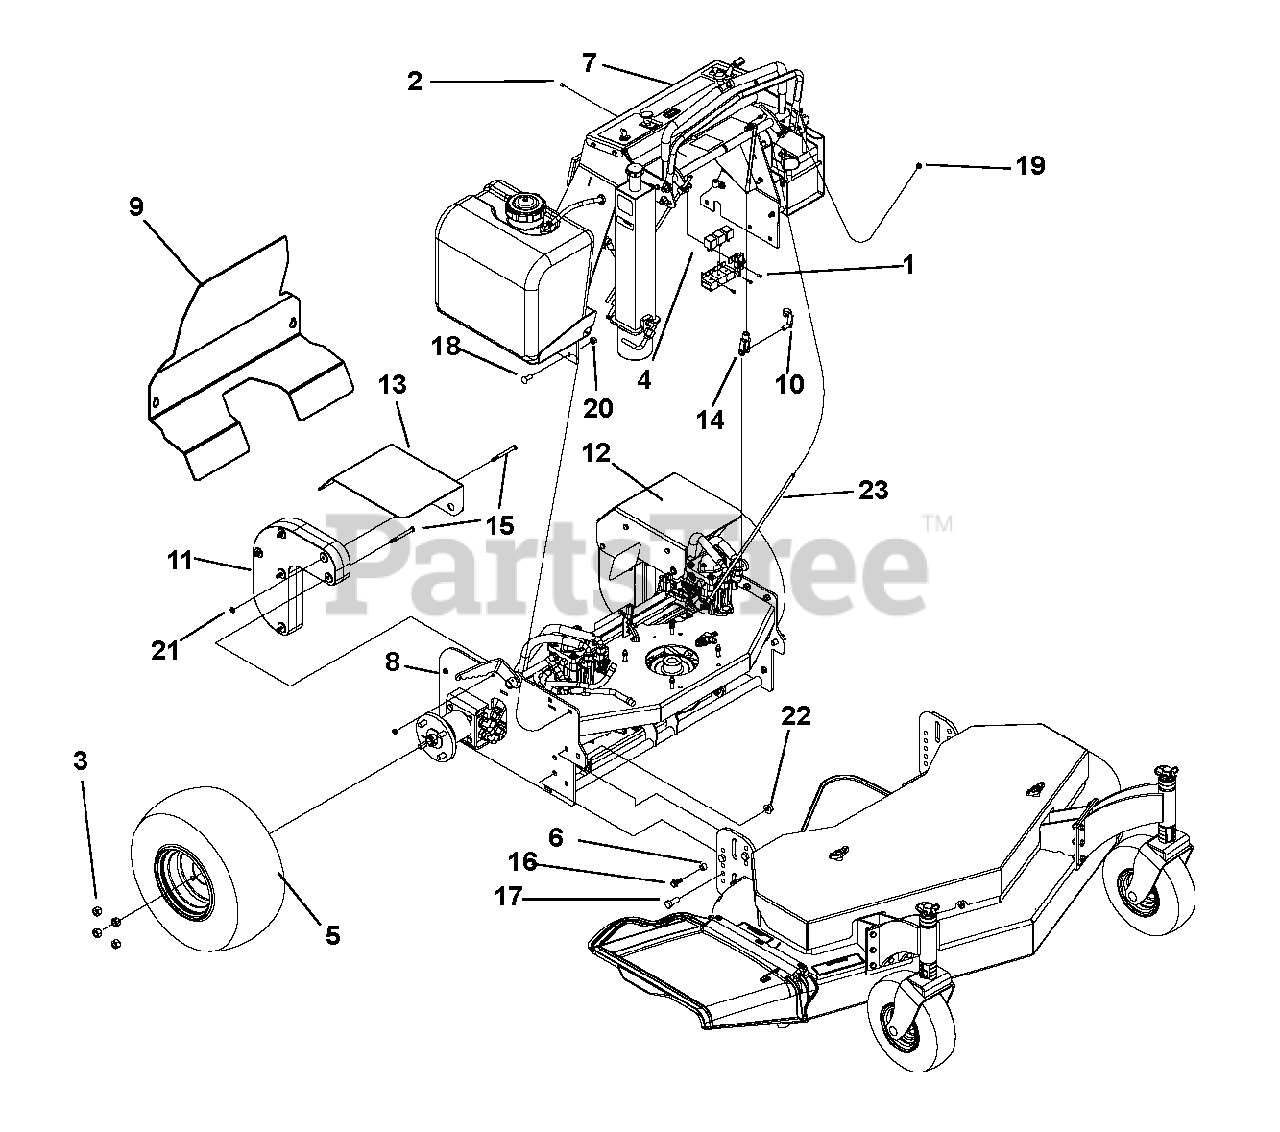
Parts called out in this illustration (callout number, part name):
1	@BLT-HEX 8-32 X .5 YWZC
2	@NUT-LK-NYL 8-32 W/INSTR YWZC
3	NUT, 1/2-20 LUG C
4	RELAY, ISO MINI ELEC.
5	ASSY, TIRE/WHL 18/8.5X8 YELLOW
6	SPACER, .625X.120X.400 Y
7	ASSEMBLY, ARIENS CONTROL PANEL
8	POWER UNIT ARIENS 52 KAI
9	GUARD, FOOT W/DECAL ARIENS 52
10	PIN, CVS SPG 3/8" YOKE SPEC Y
11	WEIGHT, CAST DRILLED
12	FENDER, LH PAINTED ARIENS
13	FENDER, RH PAINTED ARIENS
14	YOKE, 3/8-24 RH ADJUSTABLE
15	@BLT-HEX .31-18X3.25 GR5 YWZC
16	BOLT, 3/8-16X1.00 FGH 8 Y
17	@BLT-HEX .50-13X1.25 GR5 YWZC
18	@BLT-RDHDSHSQNK.38-16X1.0 G5YZ
19	NUT-HEX .312-24 YWZC
20	@NUT-SPNLK-FLG .375-16 YWZC
21	@NUT-LK-NYL .312-18 YWZC
22	NUT-SPNLK-FLG .50-13 YWZC
23	CONTROL ROD
